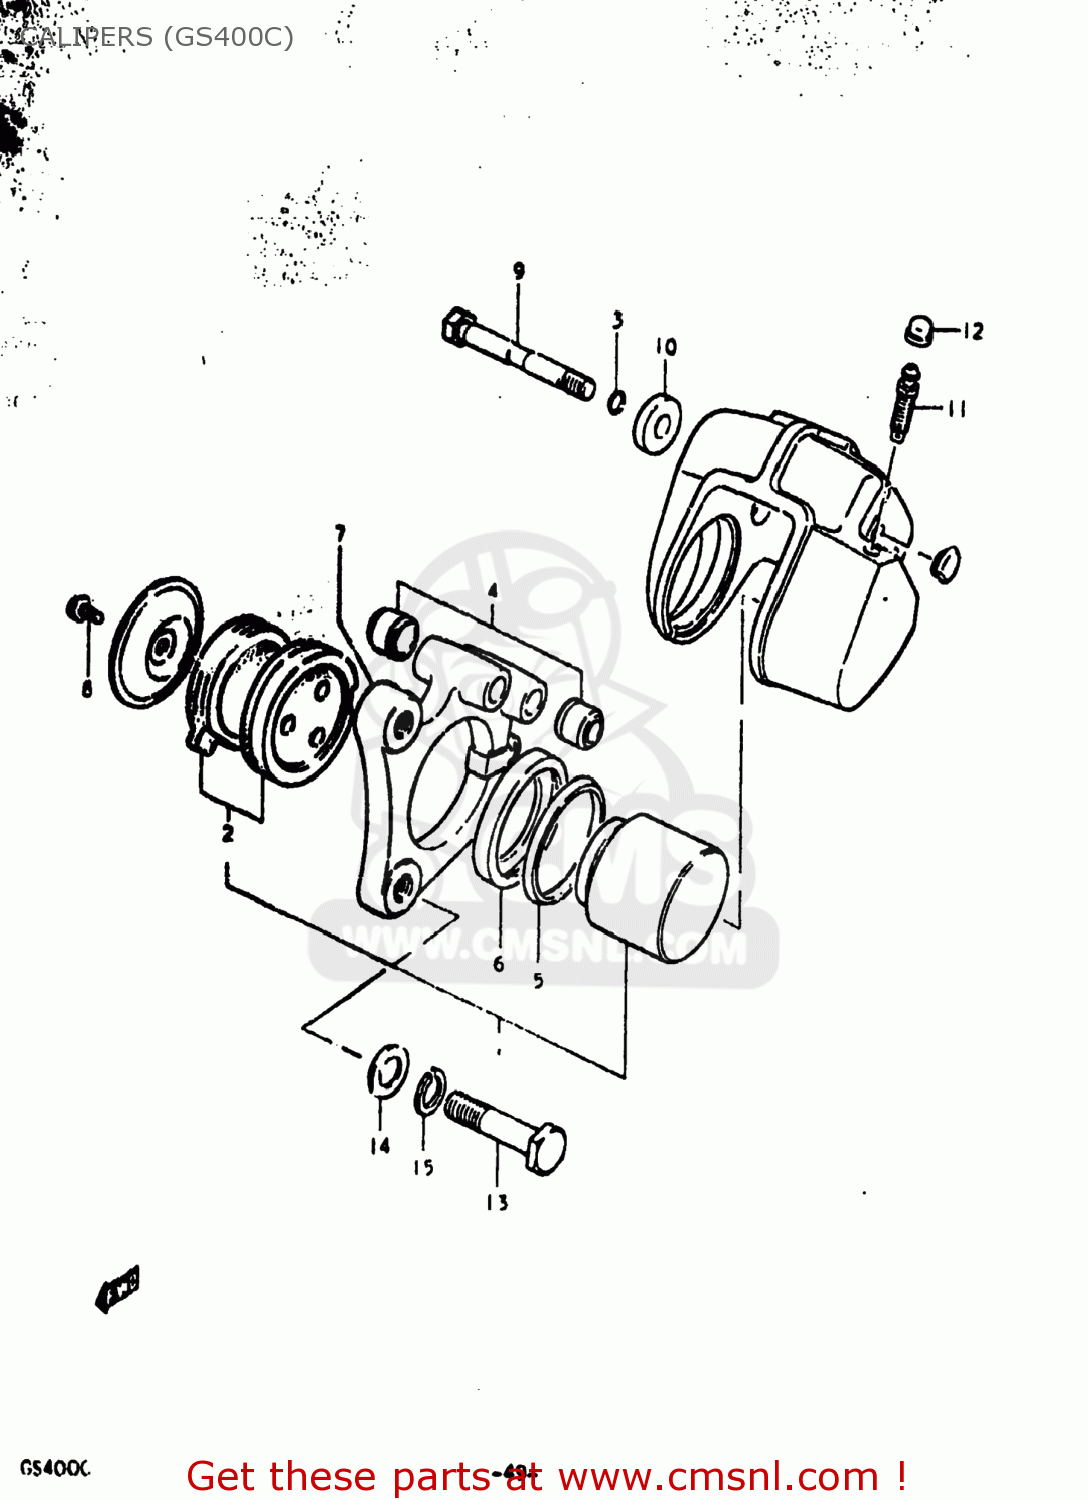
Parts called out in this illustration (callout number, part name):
1	PISTON SET
2	59302-45830 (MCA)
3	O RING
4	COVER,AXLE DUST
5	SEAL,FR CALIPE
6	BOOT,PISTON
7	HOLDER,CALIPERS
8	SCREW 6X12
9	AXLE,CALIPER
10	WASHER,AXLE
11	BLEEDER
12	CAP,BREATHER
13	BOLT
14	WASHER
15	LOCK WASHER
